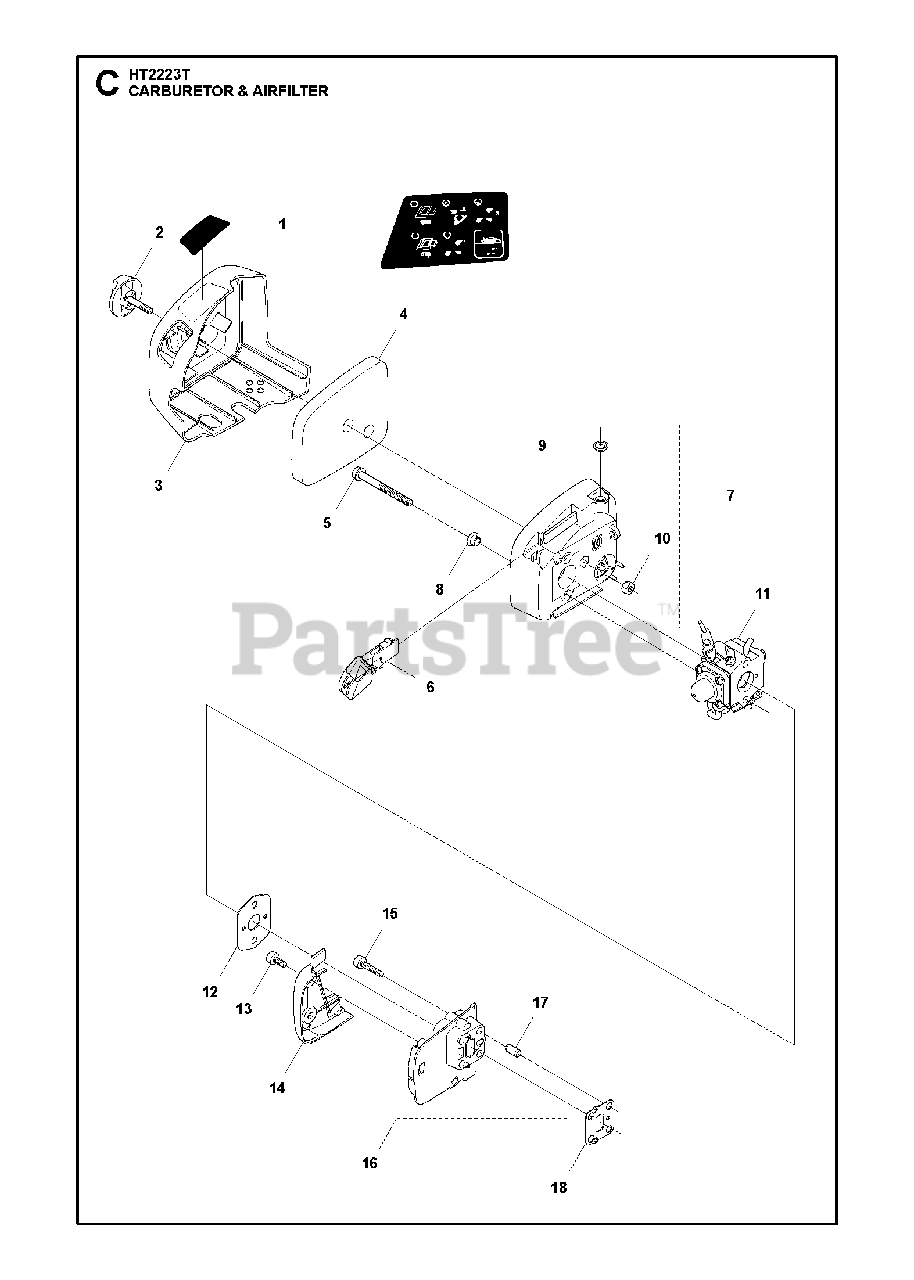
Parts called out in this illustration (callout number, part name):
4	AIR FILTER
7	FILTER HOLDER ASSY
8	RIVET TUBULAR
9	RIVET TUBULAR
10	NUT
11	CARBURETOR ASSY.
17	TUBULAR RIVET
